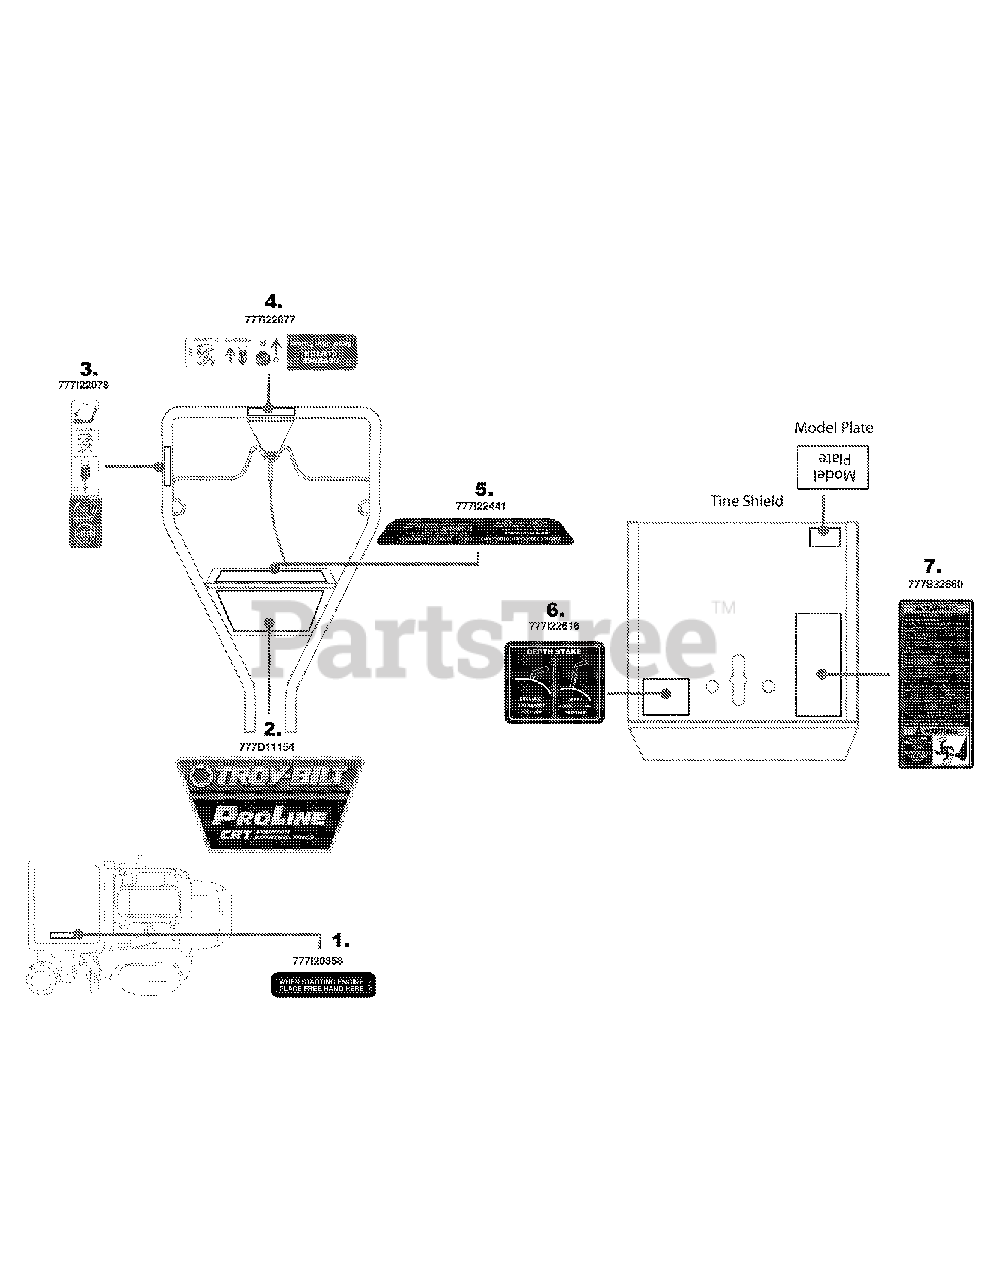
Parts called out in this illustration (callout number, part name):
1	LABEL-PLACE HAND HERE
2	LABEL-TILLER HANDLE TROY PRO LINE
3	LABEL-TILLER
4	LABEL-TILLER
5	LABEL-HNDL PNL INST CRT SPR
6	LABEL:TILLER TINE SHIELD DEPTH
7	LABEL:TILLER TINE SHIELD
